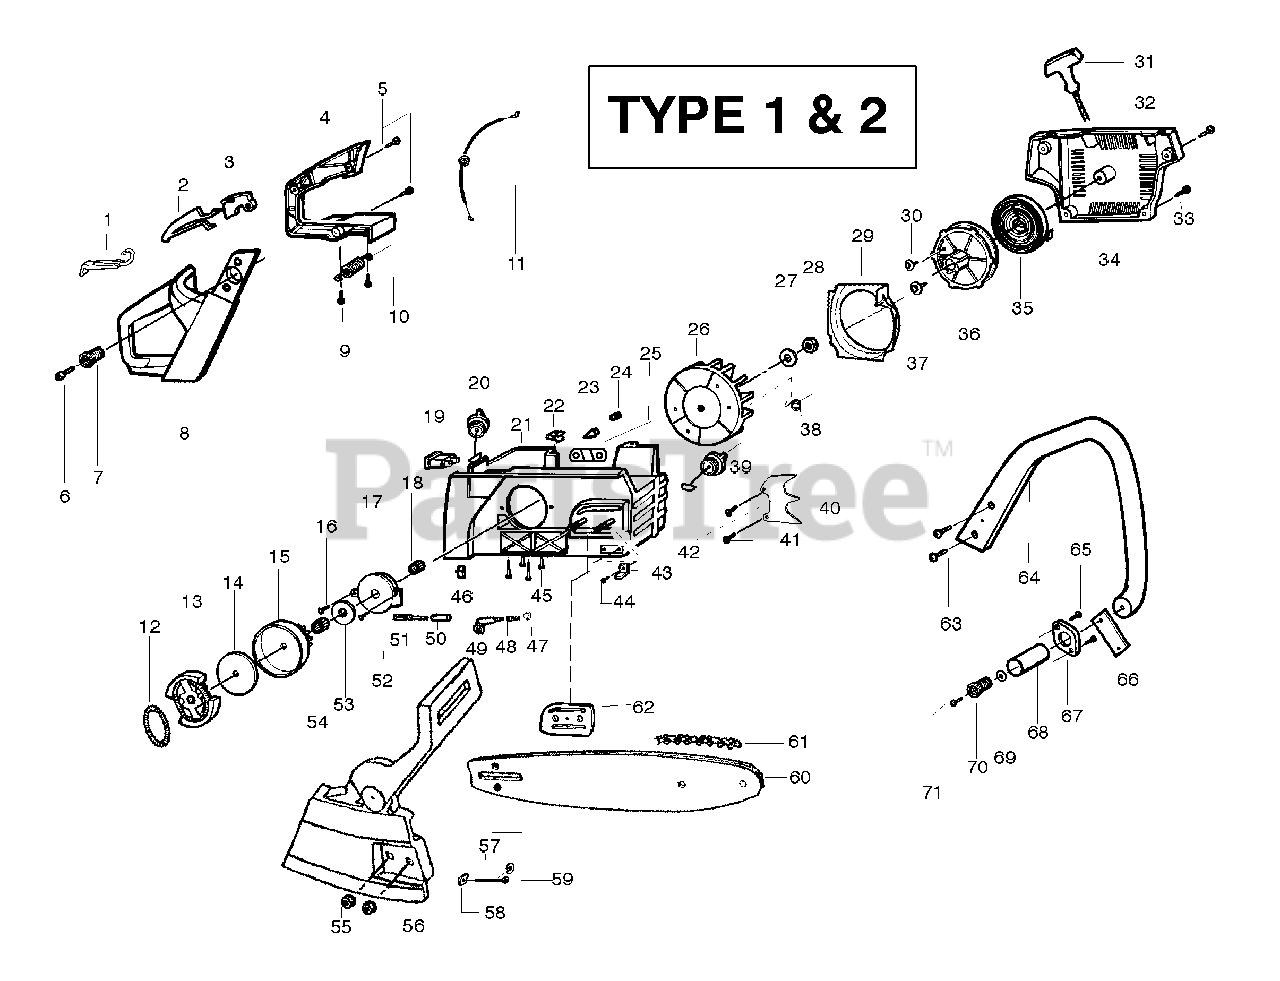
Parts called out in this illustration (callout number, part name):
1	Choke Lever
2	Throttle Lockout
3	Throttle Trigger
4	Handle Cover
7	Spring - Isolator
8	Rear Pro Handle
10	Isolator Spring
11	Throttle Cable
12	Spring - Clutch
13	Clutch Ass'y.
14	Clutch Washer
15	Kit - Clutch Drum & Bearing
17	Oil Pump Hsg.
18	Oil Pump Worm
19	Switch Kit
20	Fuel Cap Ass'y.
21	Chassis Ass'y.
22	Speed Nut
23	Check Valve
24	Vent Plug
25	Bar Stud Plate
26	Flywheel Ass'y.
29	Baffle Plate
31	Starter Handle
32	Rope Kit
34	Assy Fan Hsg
35	Recoil Spring
36	Kit - Starter Pulley
38	Spring - Starter Dog
39	Oil Cap Ass'y.
40	Assy. - Spike
41	Screw
42	Bar Bolt
43	Chain Catcher
46	Oil Seal
47	Plug-Oiler Filter
48	Oil Filter
49	Oil Pick-up
50	Oil Pump Barrel
51	Plunger & Gear Ass'y.
52	Oil Pump Ass'y.
53	Thrust Washer
54	Clutch Bearing
55	Bar Mounting Nut
56	Assy-Chainbrake
57	Retainer-Bar Adjust
58	Bar Adjusting Pin
59	Kit - Bar Adjust
60	Bar 16"
61	Chain 16"
61	Chain 18"
61	Chain 20"
62	Bar Plate
64	Handle
66	Front Strap
67	Isolator Plate
68	Spring Sleeve
70	Isolator Spring
